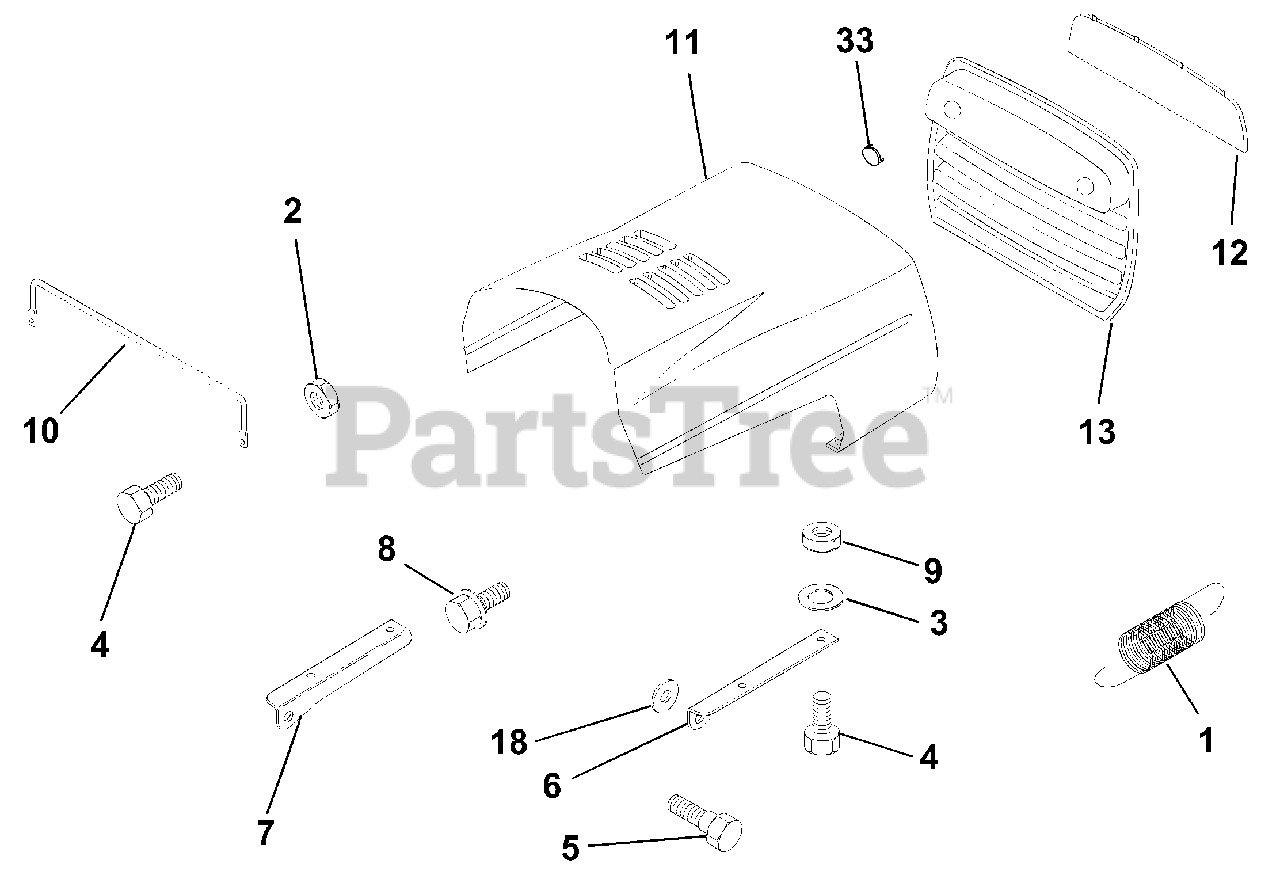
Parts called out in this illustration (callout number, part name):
1	Extension, Spring
2	Nut, Hex, Keps 1/4-20
3	Washer, 9/32 x 7/8 x 16 Ga.
4	Bolt, Hex Fin 1/4-20 x 3/4 Gr. 5
5	Bolt , Shoulder
6	Bracket, Hood R. H.
7	Bracket, Hood L.H.
8	Screw Sltd. Hex Hd W/PL Washer
9	Nut Lock W/Insert 1/4-20 UNC
10	Brace, Hood
11	Hood
12	Lens Clear Bar
18	Washer 11/32 x 11/16 x 16 Ga.
33	Plug socket light
